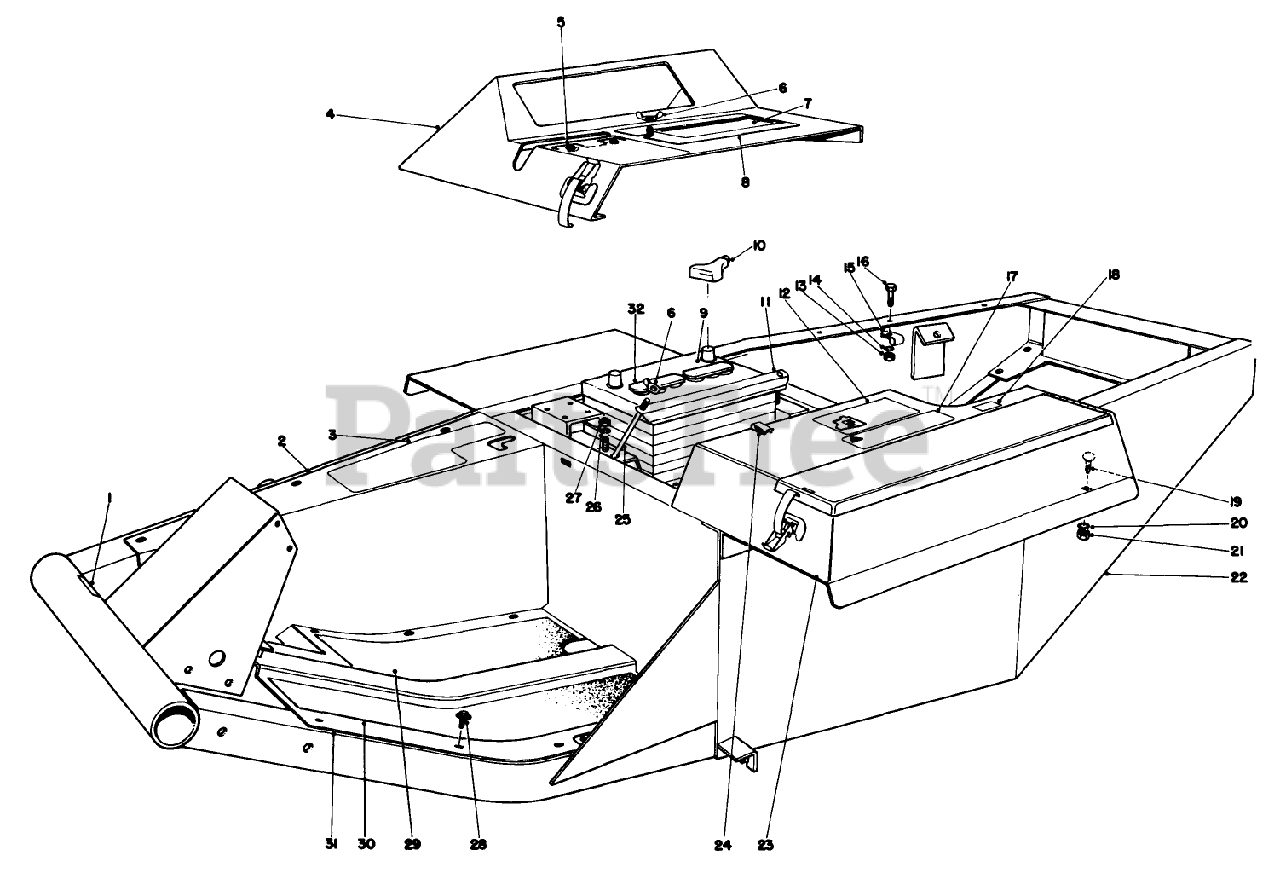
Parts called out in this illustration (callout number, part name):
1	DECAL-PEDAL, TRACTION
2	Footrest
3	Decal Caution
4	Instrument Cover
5	DECAL-PTO
6	NUT-WING
7	Decal Starting Instructions
8	Cover Battery Access
9	Battery (Incl. Ref. #32)
10	BOOT-CABLE, BATTERY
11	Battery Hold Down
12	DECAL-REFUELING
13	NUT-HEX
14	WASHER-LOCK
15	CLAMP-R
16	SCREW-HH
17	Decal Caution
18	DECAL GAS
19	SCREW-CARR
20	WASHER-LOCK
21	NUT-HEX
22	Frame
23	Tool Box
24	TINNERMAN CLIP
25	STUD-HOLDDOWN, BATTERY
26	WASHER-LOCK
27	NUT-HEX
28	SCREW-HWH
29	PAD-FLOOR PLATE, RH
30	PAD-PLATE FLOOR, LH
31	Floor Plate
32	PUSH-ON BATTERY CAP
